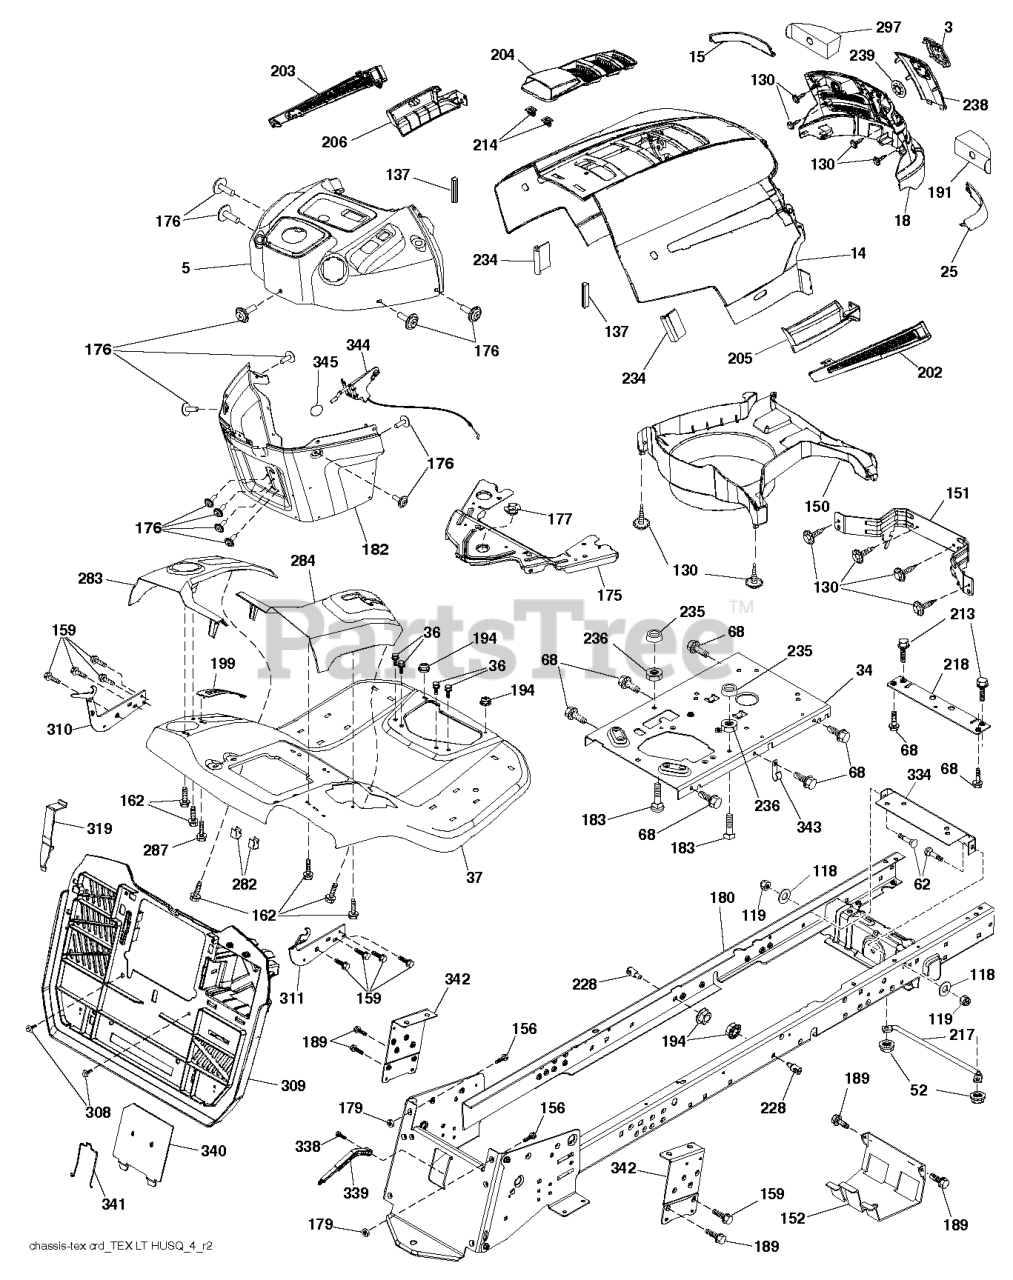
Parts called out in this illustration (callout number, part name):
3	LOGO.HUSQ.GT.LT.CROWN.H
5	SUBASM.DASH.UPPER.HLT.498
14	HOOD.HUSQVARNA.LT.ORANGE
15	LENS.HUSQVARNA LT.RH
18	GRILLE.SVC.HUSQVARNA.GREY
25	LENS.HUSQVARNA LT.RH
34	PLATE.ENGINE.10GA.CRD.GENII
36	SCREW 5/16"
37	FENDER.TEX.SRD.CRD.BASE
52	LOCKNUT
62	BOLT D
68	Screw 5/16-18 x 1/2 Hex, Self Tapping 5/16-18 x 1/2
118	WASHER
130	SCREW.#10 X 0.750.BOS
137	BUMPER DASH
151	BRACKET PIVOT
152	SHIELD.BROWNING.W/TEX
156	BOLT
159	SCREW, 3/8-16X3/4
162	SCREW.HI-LO.CONSOLE
175	CROSSMEMBER
176	SCREW.#10-24X5/8.RN.QU
177	BUSHING STEERING
180	CHASSIS WLDT TEX CRD
182	DASH DASH. LOWER. PREDATOR. LT
183	BOLT.5/16-18X1-1/4 FULL THD
189	SCREW
191	INSERT.REFLECTIVE.RH.
194	NUT LOCK HEX FLANGE 5/16-18
199	PLATE DECK LIFT
202	VENT.SIDE.HUSQVARNA.LT.RT
203	VENT.SIDE.HUSQVARNA.LT.LFT
204	SUBASM.TOP.VENT.HUSQ.LT
205	SKIRT.SIDE.HUSQVARNA.LT.RT
206	SKIRT.SIDE.HUSQVARNA.LT.LEFT
213	BOLT
214	CLIP.RETAINER.TINNER.
217	ROD.PIVOT.HOOD
218	X-PIECE.HOOD.STOP.NON/
228	STUD.FASTNER.W/ANTI-ROTATE
234	BUMPER.HOOD.TEX.HUSQVARNA
235	SPACER FENDER
236	NUT.CENTERLOCK.5/16-
238	TRIM.HUSQ LT.668
282	CLIP.RETAINER.CONSOLE.LT.HUSQ
283	CONSL.DECKLIFT.LH.SRD.TEX.CRD
284	CONSL.SHFT.PEDAL.RH.SRD.TEXCRD
287	SCREW 1/4X20
297	INSERT REFLECTIVE
308	BOLT.5/16-18UNCX3/4 W/SEMS.BLK
309	BACKPLATE.TEX.CRD
310	LH.ADJUST.HANGER.BRACKET.ASM
311	RH.ADJUST.HANGER.BRACKET.ASM
319	BRACKET.ACTUATOR.BAGGER.SRD
334	BRACKET.ENGINE
338	BOLT BOLT SHOULDER
339	LEVER LEVER BAGGER
340	DOOR.PNT.BATTERY.TRY.TEX.CRD.
341	LATCH
342	SUPPORT SUPPORT FENDER
343	CLIP CLIP
344	CONTROL.EZ.MULCH.TEX/CRD
345	RP KNOB.OVAL.TAPERED.3/8-16BLK
